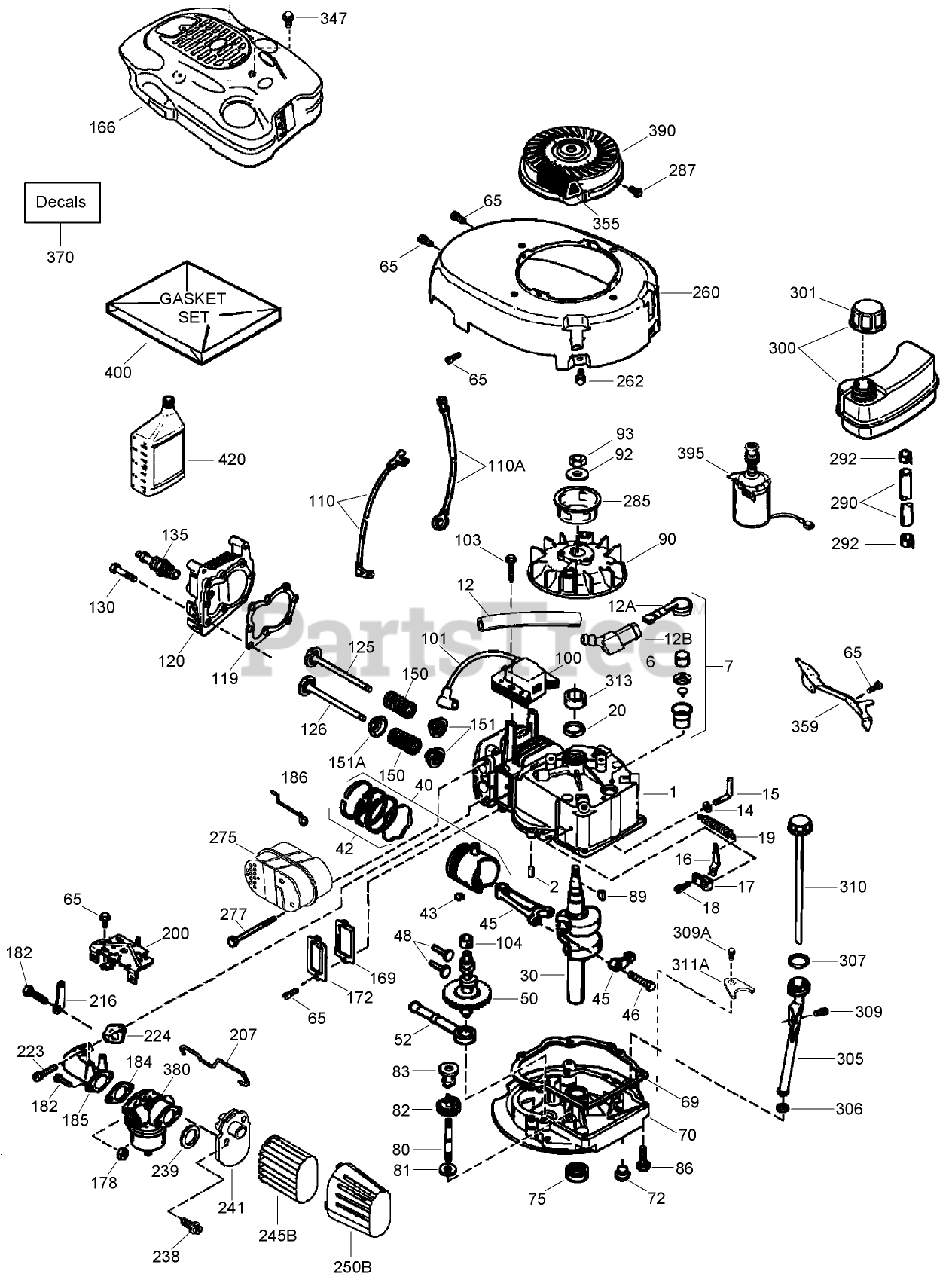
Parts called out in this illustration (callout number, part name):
1	Cylinder ASM
2	Pin-Dowel
6	Element-Breather
7	Breather ASM (Incl. Ref. #6 and 12A)
12	Tube-Breather
12A	Breather Cover and Tube (Incl. Ref. #12B)
12B	Elbow-Tube, Breather
14	Washer-Flat
15	Rod, Governor (Incl. No. 36)
16	Lever-Governor
17	Clamp-Lever, Governor
18	Screw (T-15, 8-32 x 19/64)
19	Spring-Extension
20	Seal-Oil
30	Crankshaft
40	Piston, Pin and Ring Set (STD)
40	Piston, Pin and Ring Set (.010 O S)
42	FITTING - TANK 3/4"
42	FITTING - TANK 1"
43	Ring-Retaining, Piston Pin
45	Connecting Rod ASM (Incl. Ref. #46)
46	Bolt-Rod, Connecting
48	Lifter-Valve
50	Camshaft (Exhaust MCR) (Incl. Ref. #104)
52	Oil Pump ASM
65	Screw (10-24 x 9/16)
69	Gasket-Flange, Mounting
70	Mounting Flange ASM
72	Plug-Drain, Oil
75	Seal-Oil
80	Shaft-Governor
81	Washer-Flat
82	Governor Gear ASM
83	Spool-Governor
86	Screw (1/4-20 x 1-1/4)
90	Flywheel
92	Washer-Belleville
93	Nut-Flywheel
100	Ignition-State, Solid
101	Cover-Spark Plug
103	Screw (T-15, 10-24 x 15/16)
104	Bushing-Cam
110	Wire-Ground
110A	Wire ASM
119	Gasket-Head, Cylinder
120	Head-Cylinder
125	Valve-Exhaust (Std.) (Incl. Ref. #151)
126	Valve-Intake (Std.) (Incl. Ref. #151 and 151A)
130	Screw (5/16-18x1-1/2)
